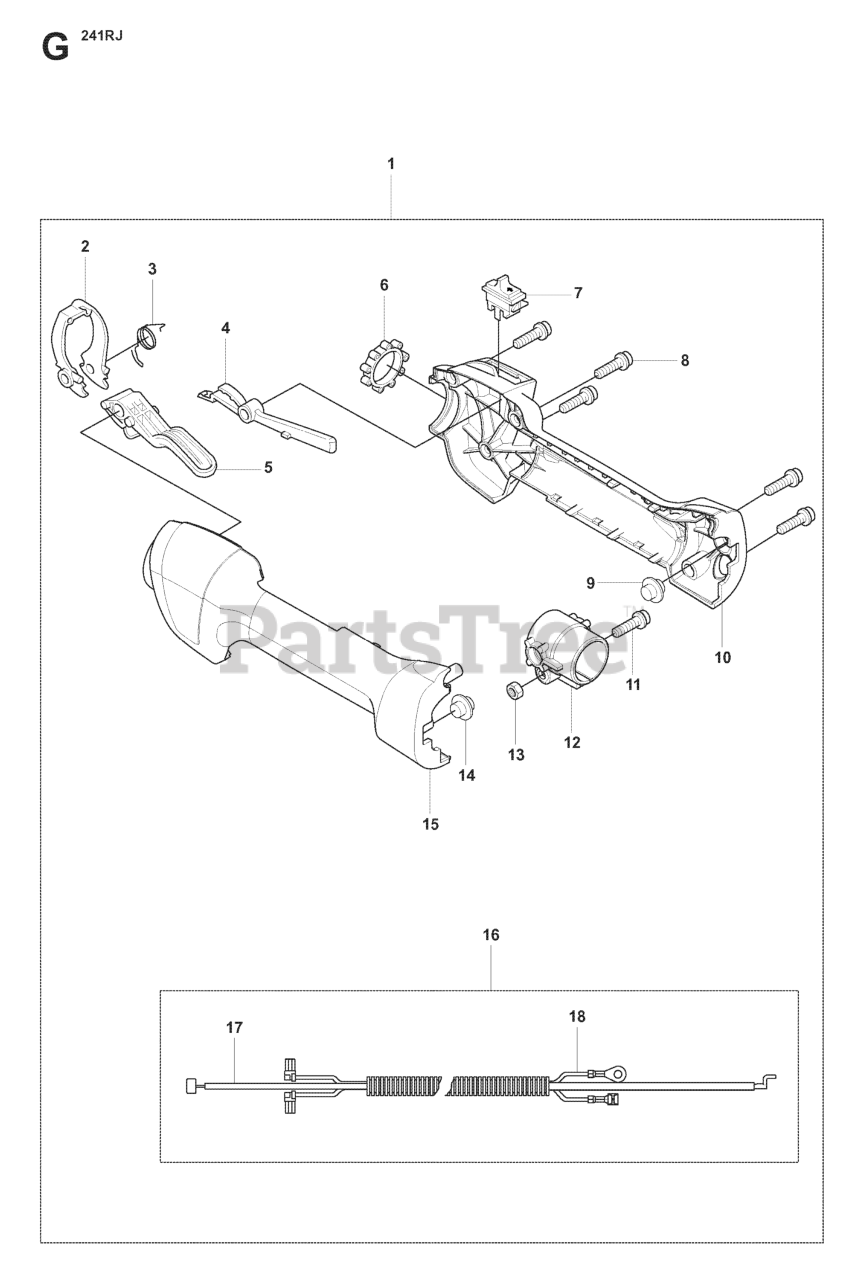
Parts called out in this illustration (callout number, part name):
1	THROTTLE HANDLE CPL
3	RETURN SPRING
4	THROTTLE LOCK
5	THROTTLE TRIGGER
6	VIBRATION DAMPER
7	STOP BUTTON
9	VIBRATION ABSORBER
14	VIBRATION ABSORBER
16	WIRING ASSY.
17	THROTTLE WIRE ASSY
18	SHORT CIRCUIT CABLE
